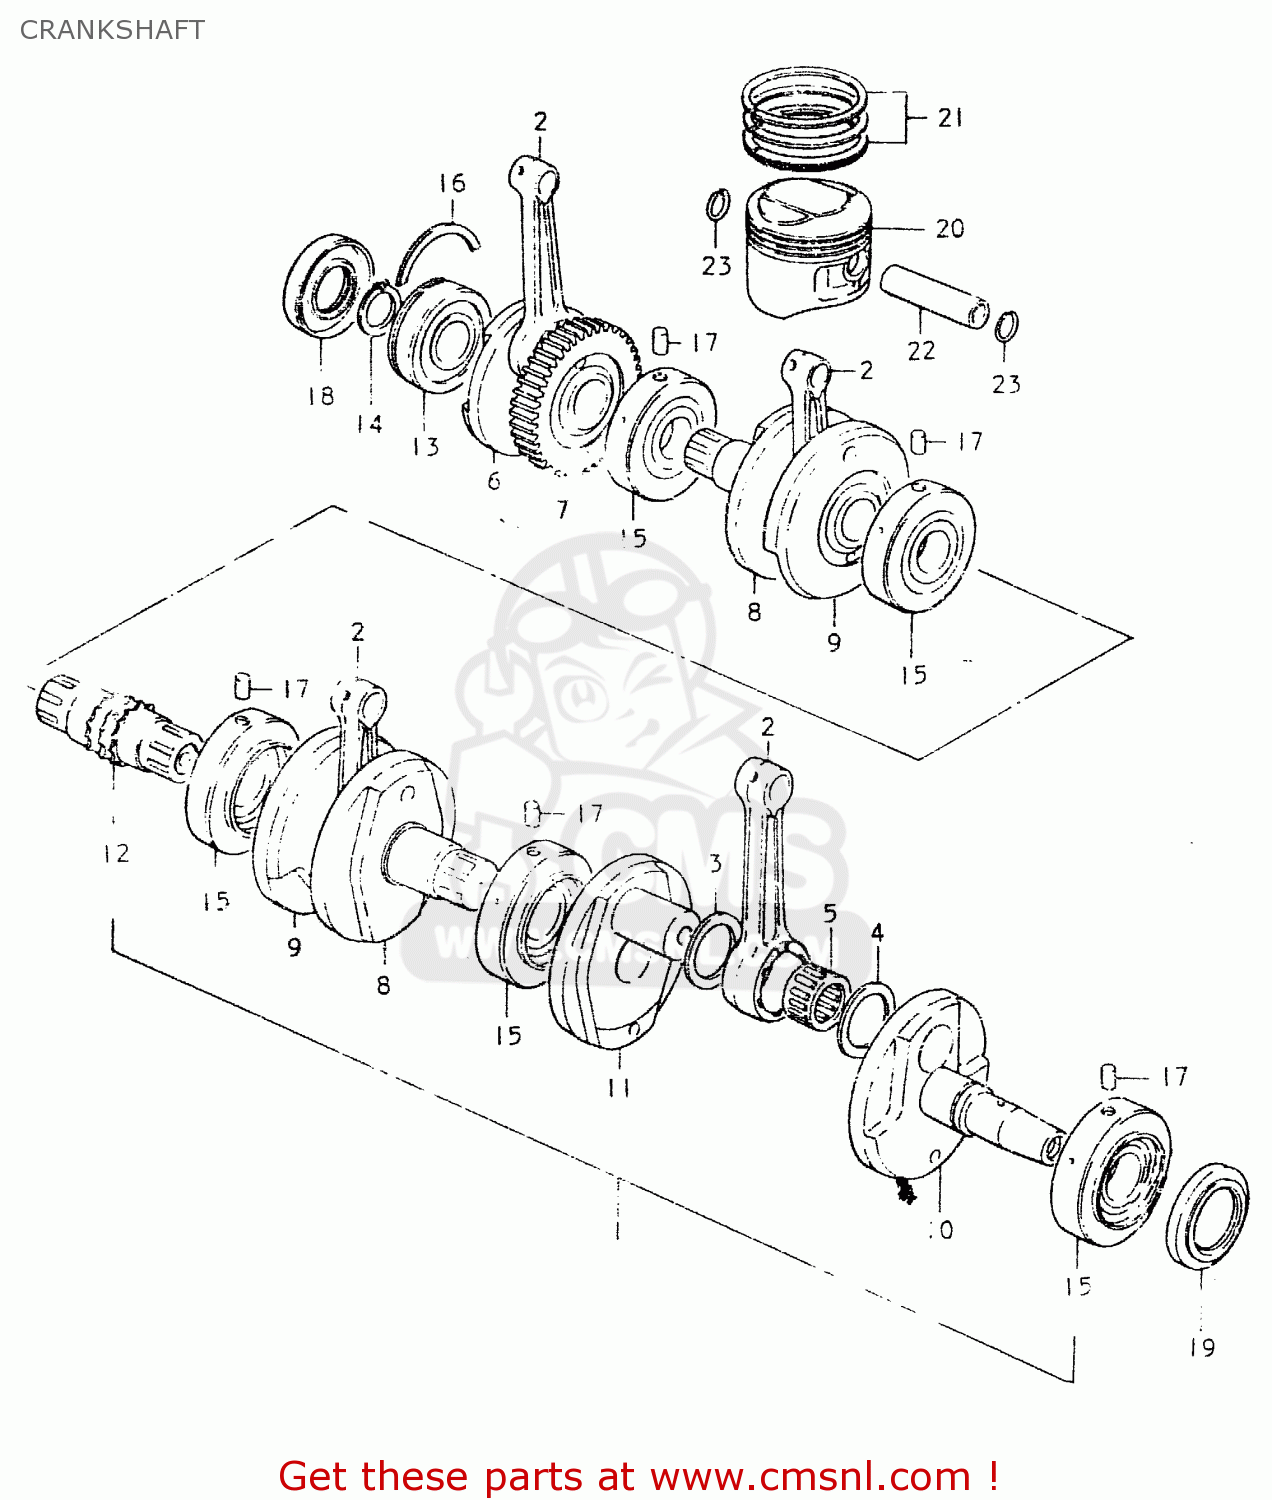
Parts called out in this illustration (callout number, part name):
1	CRANKSHAFT ASSEMBLY
2	ROD,CONNECTING
3	WASHER (28X48X2)
4	WASHER(28X48X1)
5	ROLLER BEARING (28X38X16.8)
6	CRANKSHAFT
7	WEB,CRANK
8	CRANKSHAFT
9	WEB,CRANK,MIDDLE
10	CRANKSHAFT,LEFT
11	WEB,CRANK,LEFT
12	SHAFT,TIMING CHAIN DRIVE
13	BEARING(30X72X19)
14	CIRCLIP,30MM
15	BEARING
16	C RING
17	PIN
18	SEAL,OIL(30X72X11)
19	OIL SEAL
20	PISTON
21	RING SET,PISTON
22	PIN,PISTON 16MM
23	CIRCLIP
